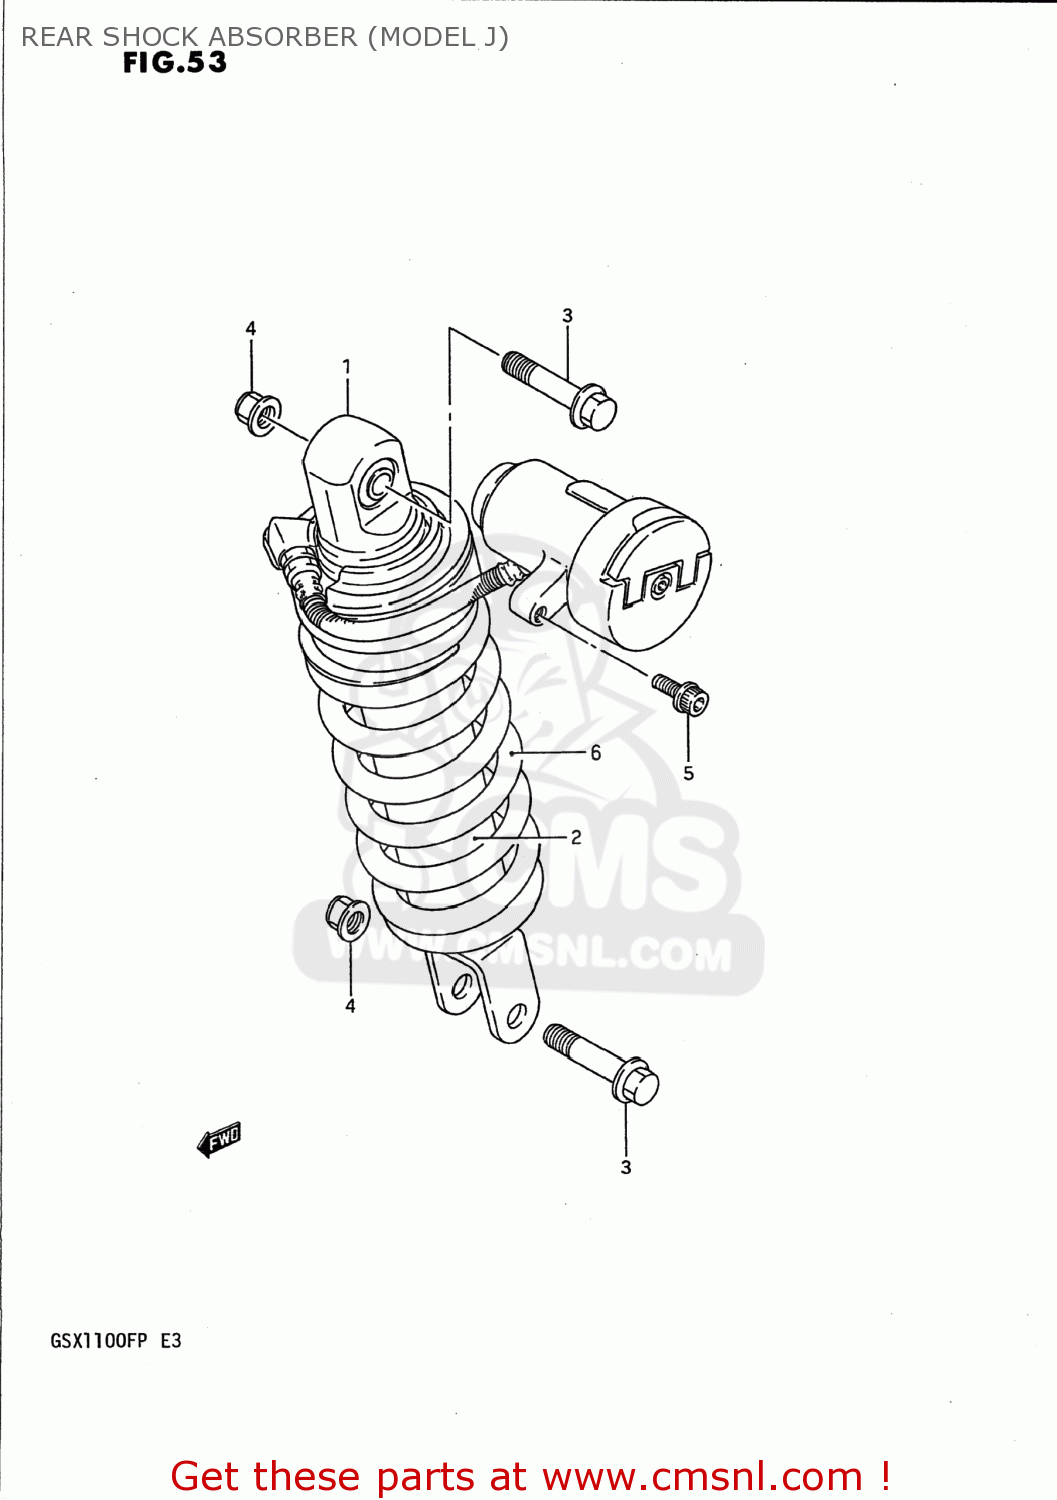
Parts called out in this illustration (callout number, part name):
1	ABSORBER ASSEMBLY,REAR SHOCK
2	ADJUSTER,SPRING
3	BOLT(10X54)
4	NUT
5	BOLT
6	SPRING,REAR SHOCK ABSORBER
